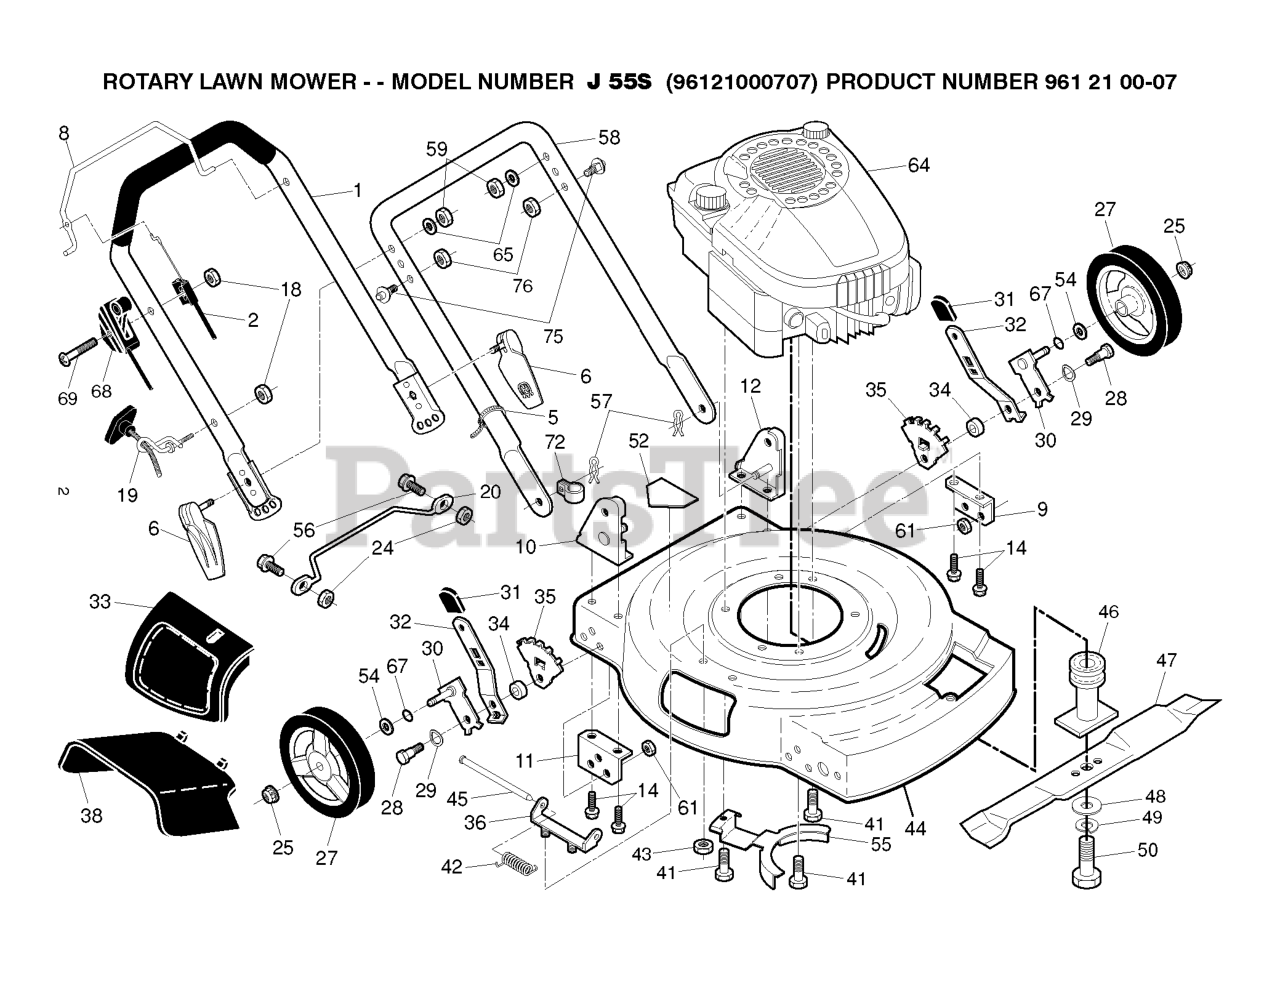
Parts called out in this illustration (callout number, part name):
1	Upper Handle
2	ENGINE ZONE CONTROL CABLE
5	TIE GUIDE
6	QUICK.ASM.RELEASE.BLACK
8	BAIL.COMF.FWGD.668.ORANGE.WALK
9	GUARD.SLKSCR.BELT.
10	Handle Bracket Assembly, RH
11	Support Bracket, Handle, RH
12	Handle Bracket Assembly, LH
14	SCREW.5/16-18X3/4
18	NUT
19	RB GUIDE.ROPE.STD.BLK.ZIN WSL
20	FOOTGUARD.WIREFORM.CE
25	NUT.HEX.FLANGE.3/8-16.LO(3 2)
27	WHEEL & TIRES ASSY, FRONT
28	BOLT SHOULDER 3/8 -16X1
29	WASHER.CURVED.CYLINDRICAL
30	AXLE ARM ASSY.
31	SELECTOR KNOB
32	SPRING.SEL.EXT.21.DOMED.12/14
33	DOOR.MULCH.22.EZ.MULCH.GREY
34	SPACER.HEIGHT.ADJUSTER
35	BRACKET.ADJ.WHEEL.5POS.ADS
36	BRACKET.ASM.HOUSING.EZ.MUL
38	DEFLECTOR.GUARD.22..EZ.MULCH
41	BOLT 3/8-16X1-1/8
42	TORSION SPRING
43	LOCKNUT.NYLOC.1/4-20
44	Kit, Mower Housing
45	ROD.HINGE.COMBI-C
46	ADAPTER.BLADE/PULLEY.25M
47	Blade, 22"
48	WASHER,HARDEN
49	LOCKWASHER
50	SCREW, HEX HD 3/8-24 X 1-3/8
52	DECAL.INTERNATIONL.CUTFINGER
54	WASHER.FLAT.1/2
55	BRACKET.ENG/BELTKEEPER.BZP
57	HAIRPIN COTTER
58	HANDLE LOWER EZ 2POS GRAY
59	Locknut, Hex 1/4-20
61	LOCKNUT
65	WASHER.20X8.5
67	O-RING..070X.487.NEOPRENE
68	Control Throttle
72	CLIP.CABLE.BLK
75	STUD.QUICK.ADJUST
76	NUT.LOCK.5/16-18
